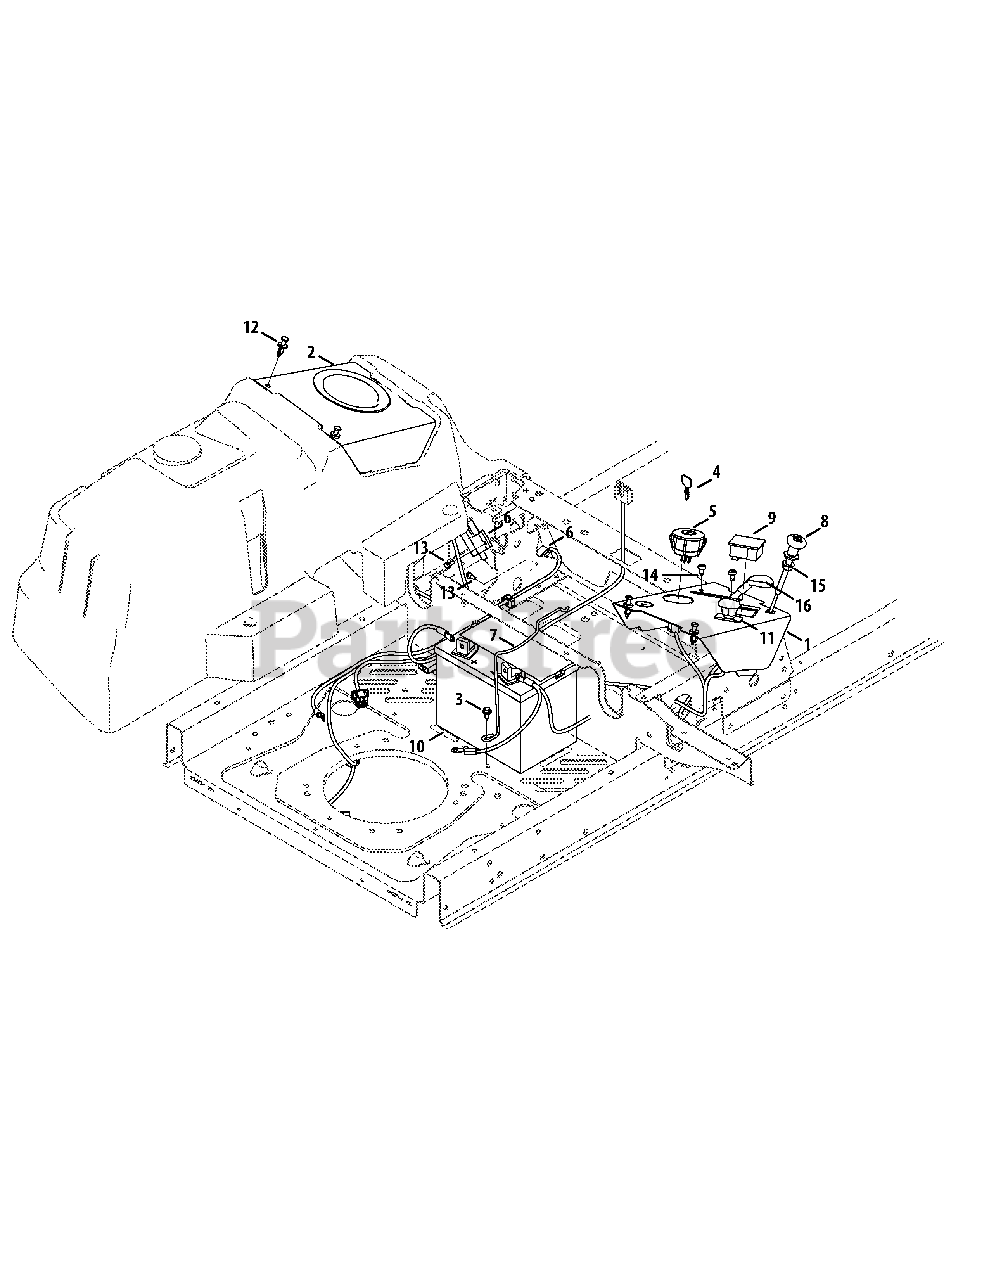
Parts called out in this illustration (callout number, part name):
1	Console Cover, RH
2	Console Cover, LH
3	Hex Washer Screw, 1/4-20 x .625
4	Key, Assembly
5	Key Switch
6	Interlock Switch
8	Choke Cable
9	Hour Meter/Service Minder
11	Electric PTO Switch
12	Plastic Rivet
13	Shoulder Screw, #10-32 x .500
14	Screw, 1/4-20 x .50
15	Flange Lock Nut, 3/8-16
16	Throttle Cable, Confidant
16	Throttle Cable, Command
